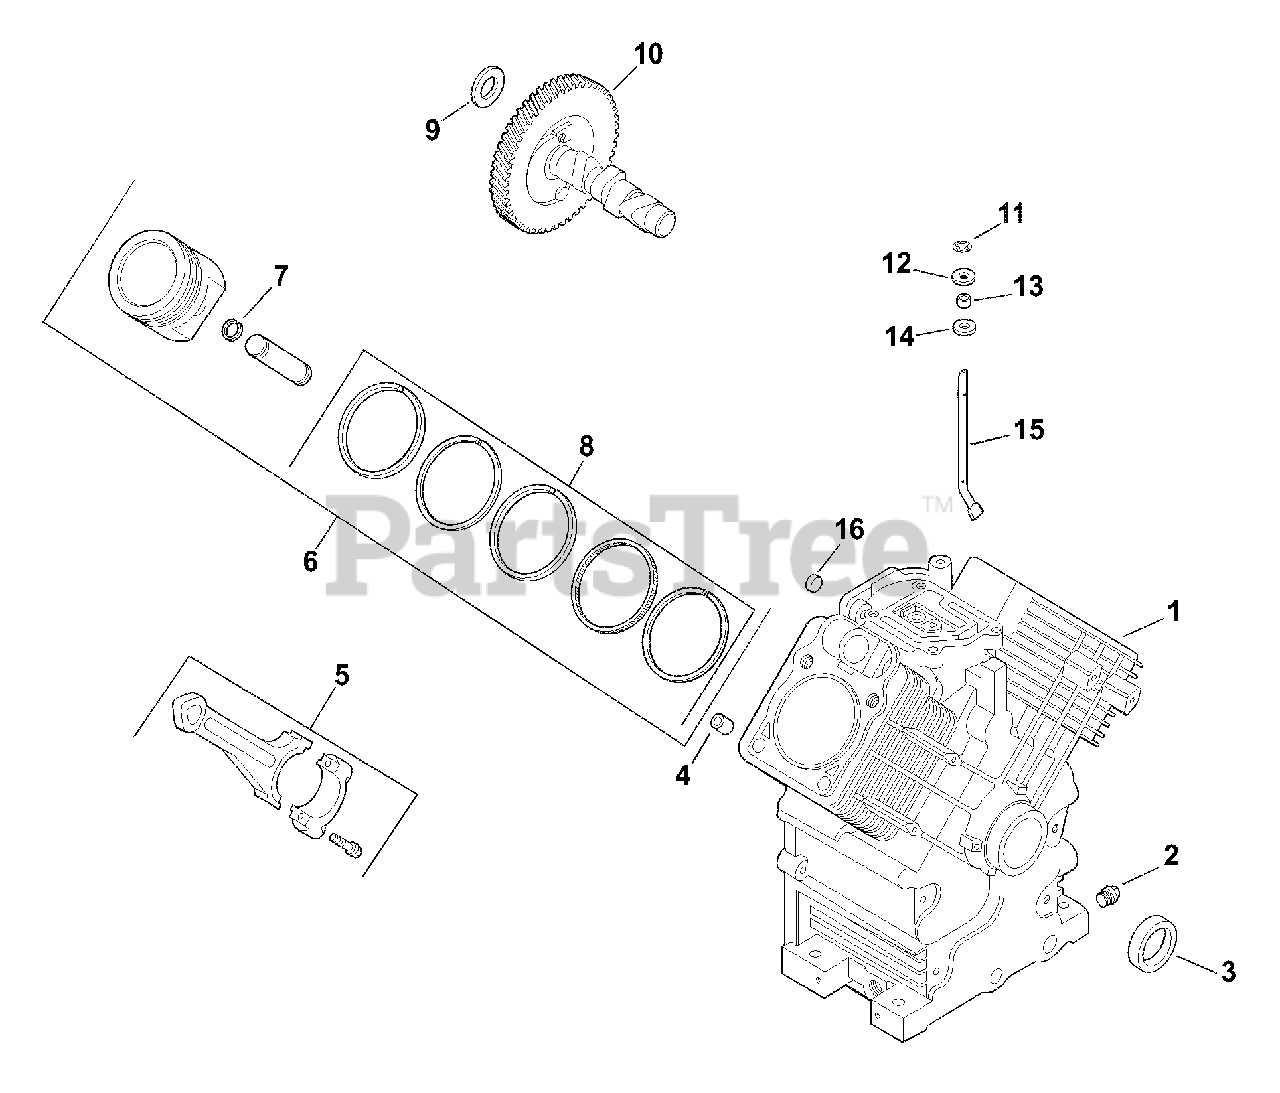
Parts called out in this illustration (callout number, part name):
1	Crankcase
2	Plug, hex. head 3/8"
3	Seal, front oil
4	Pin, locating
5	Connecting Rod (Std.)
6	Piston w/Ring Set (Std.)
7	Retainer, piston pin
8	Ring Set (Std. & .08)
9	Shim, camshaft (A.R.) red
10	Camshaft
11	Retainer, ring
12	Washer, plain 9 mm
13	Seal, governor cross shaft
14	Washer, plain 1/4"
15	Shaft, governor cross
16	Plug, cup
